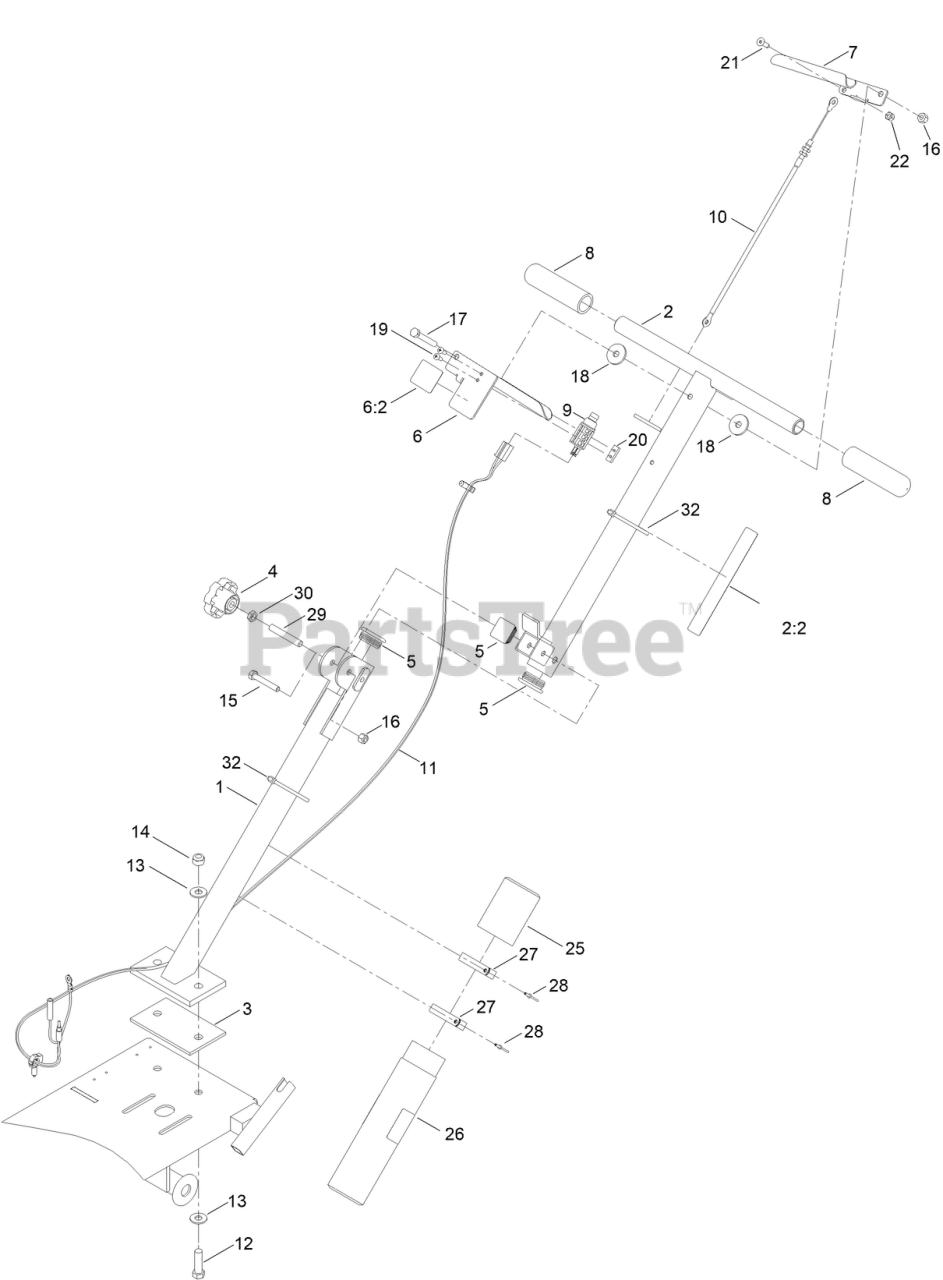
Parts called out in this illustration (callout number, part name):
1	HANDLE-LOWER
2	HANDLE ASM
2:2	DECAL-CAUTION
3	GASKET-HANDLE
5	PLUG-TUBE
6	PLUNGER HANDLE ASM
6:2	DECAL-ENGAGE
7	THROTTLE HANDLE ASM [BLK-TXT]
8	GRIP-HANDLE
9	SWITCH-PLUNGER, NC (W/COVER)
10	CABLE-THROTTLE
11	HARNESS-WIRE
12	SCREW-HH
13	WASHER-FLAT
14	NUT-LOCK, NI
15	SCREW-HH
16	NUT-LOCK, NI
17	SCREW-HH
18	WASHER
20	PLATE-TAPPED
21	SCREW-TORX
22	NUT-LOCK, NI
25	CAP-HOUSING
26	TUBE-MANUAL
27	CLAMP-R
28	RIVET-POP
29	SCREW-HSH
30	NUT-JAM
32	TIE-CABLE
